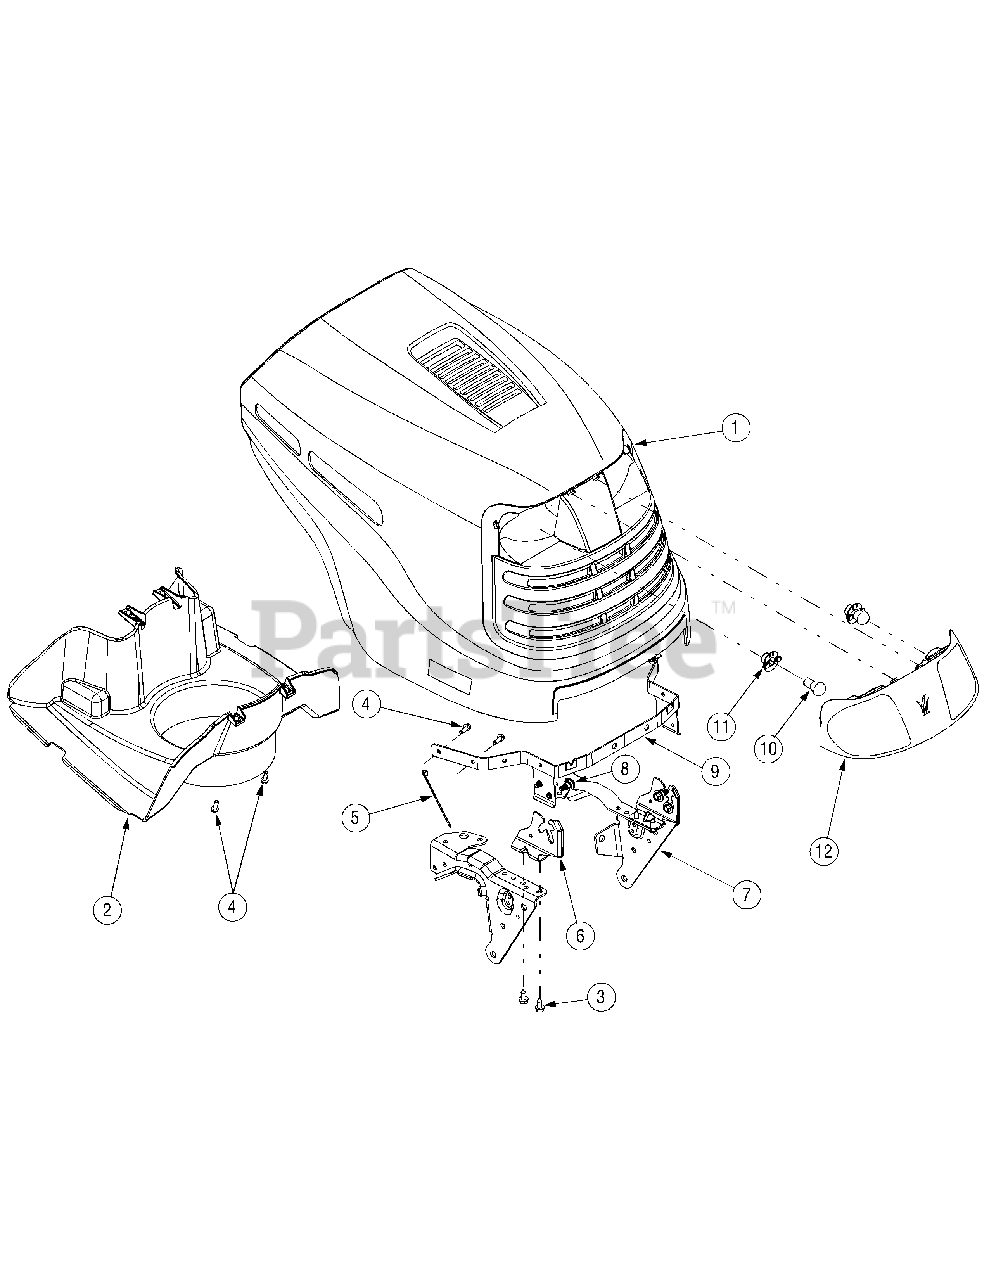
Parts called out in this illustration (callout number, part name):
1	Hood
2	Hood Plenum (LT1042 & LT1045)
2	Hood Plenum (LT1046 & LT1050)
3	Self-tapping Screw, 5/16-18 x.625
4	Screw, 1/4-15 x .75
5	Cable Tie
8	Shoulder Screw, .43 x .29 x 5/16-18
10	Miniature Lamp, 12 V
11	Lamp Socket
12	Headlight Lens
